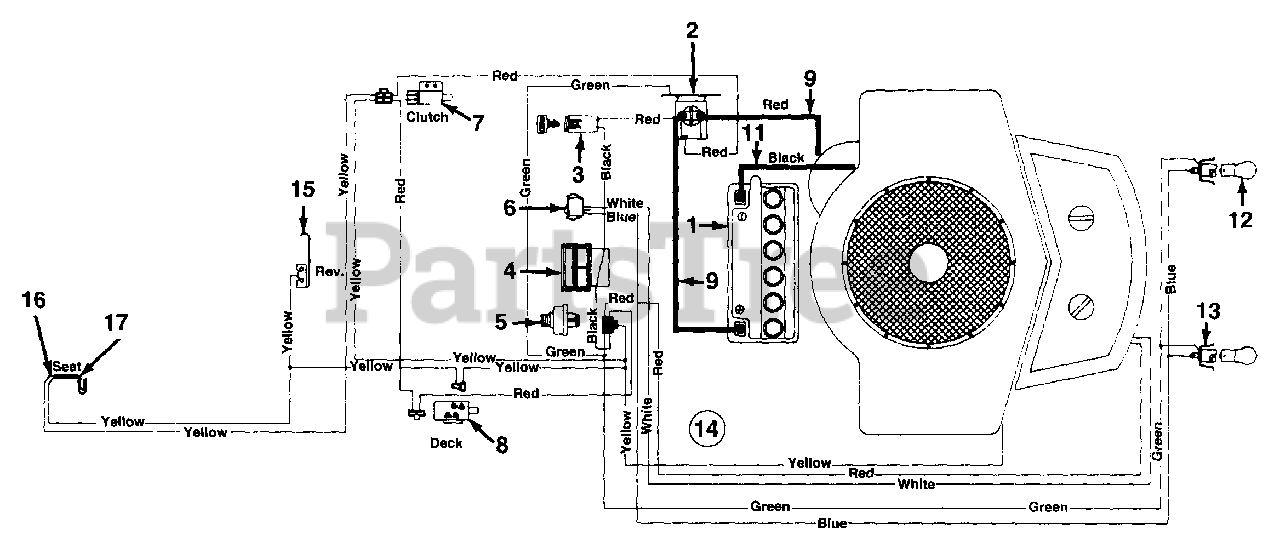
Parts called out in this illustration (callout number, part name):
1	Battery (275 Cold Crank Amps)
2	Solenoid
3	Fuse 7.5 Amp
4	Ammeter
5	Ignition Switch
6	Light Switch
7	Safety Switch (Clutch)
8	Safety Switch (PTO)
9	Electric Wire 14" Lg.
11	Ground Wire 7.5" Lg.
12	Lamp
13	Socket
14	Wire Harness
15	Spring Switch (Reverse)
16	Spring Switch (Seat)
17	Spring Switch (Seat)
